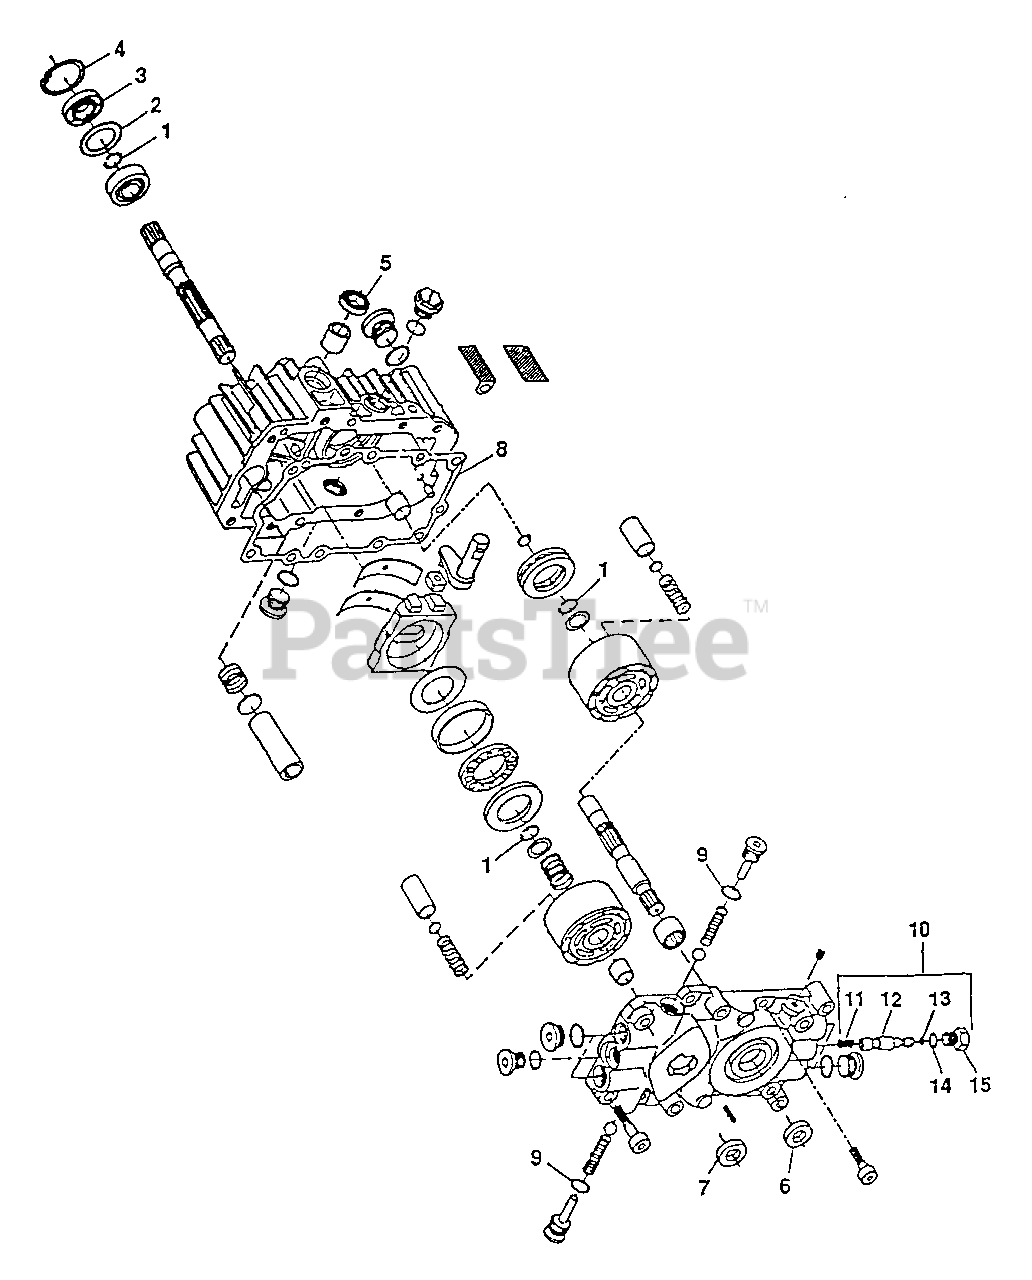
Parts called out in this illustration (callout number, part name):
1	RING-RETAINING
2	SPACER
3	SEAL-LIP
4	RING-RETAINING
5	SEAL-LIP
6	SEAL-LIP
7	SEAL-LIP
8	GASKET-CENTER SECTION
9	O-RING
10	BY-PASS VALVE KIT COMPLETE
11	SPRING-HELICAL COMP
12	BY-PASS SPOOL
13	O-RING
14	O-RING
15	PLUG-BY-PASS
